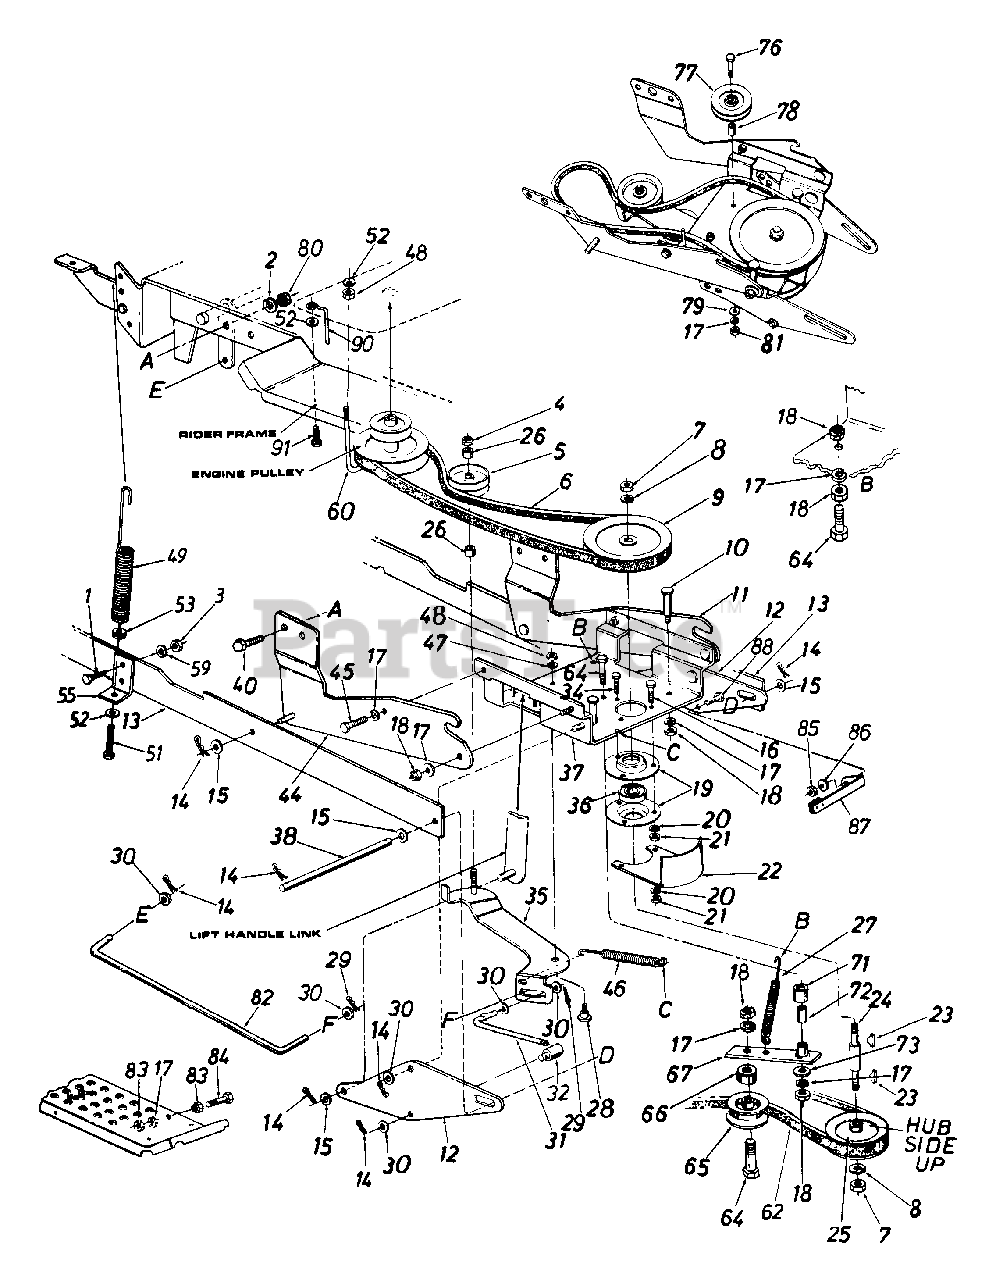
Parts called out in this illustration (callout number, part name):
1	Hex Bolt 1/4-28 x 1" Lg. Grade 5
2	L-Wash. 1/4" I.D.
3	hex Nut 1/4-28 Thd.
4	Hex Cent. L-Nut 3/8-16 Thd.
5	Idler Pulley
6	"V"-Belt
7	Hex Jam Nut 5/8-11 Thd
8	I -Wash. 5/8" I.D.
9	Pulley .627" I.D. x 6.5" O.D.
10	Shoulder Bolt
15	Fl-Wash
16	Hex Bolt 5/16 x 1.25" Lg.
17	L-Wash. 3/8" I.D.
18	Hex Jam Nut 3/8-16 Thd.
19	Bearing Housing
20	L-Wash. 5/16" I.D.
21	Hex Nut 5/16-18 Thd.
24	Pulley Spindle
25	Pulley.628" I.D. x 5.56" O.D.
26	Spacer.383" I.D. x .503"
27	Extension Spring 5.25" Lg.
28	Shoulder Bolt
29	Cotter Pin 3/32" Dia.
30	Fl-Wash..385" I.D. x .87"
31	Control Rod (Clutch)
32	Ferrule
34	Hex Sems Scr. 5/16-18 x .75" Lg.
35	Clutch Idler Brkt. Ass'y.
36	Ball Bearing
37	Channel Ass'y.
38	Lift Handle Shaft
40	Hex Self-Tap Scr. 1/4-20 x .75" Lg.
46	Extension Spring
47	L-Wash. 5/16" I.D.
48	Hex Nut 5/16-18 Thd.
49	Helper Spring
51	Hex Bolt 5/16-18 x 1.5" Lg.
52	Bell-Wash..345" I.D. x 88"
53	Spring Insert
60	J-Bolt 5/16-18 Thd.
62	"V"-Belt
64	Hex Bolt 3/8-16 x 2.0" Lg.
65	Idler Pulley
66	Spacer .385" I.D. x .503"
67	idler Arm Ass'y.
71	Spacer 380" I.D.
72	Spacer.3775" I.D.
73	Fl-Wash. 3/8" I.D. x 1" O.D.
76	Hex Bolt 3/8-16 x 2.5" Lg. (Grade 5)
77	Idler Pulley .38" I.D. x 3.06" O.D.
78	Spacer .385" I.D. x .76" Lg.
79	Fl-Wash..39" I.D. x 1-3/4" O.D.
80	Hex L-Nut 1/4-20 Thd.
81	Hex Nut 3/8-16 Thd.
82	Clutch Control Rod
83	Hex Nut 3/8-24 Thd.
84	Hex Bolt 3/8-24 x 2.25" Lg.
85	Hex Nut 3/8-16 Thd.
86	Bell-Wash. 3/8" I.D.
87	Auger Brake Brkt. Ass'y,
88	Hex Bolt 3/8-16 x 5/8" Lg.
90	Belt Guard
91	Hex Bolt 5/16-18 x .75" Lg.
